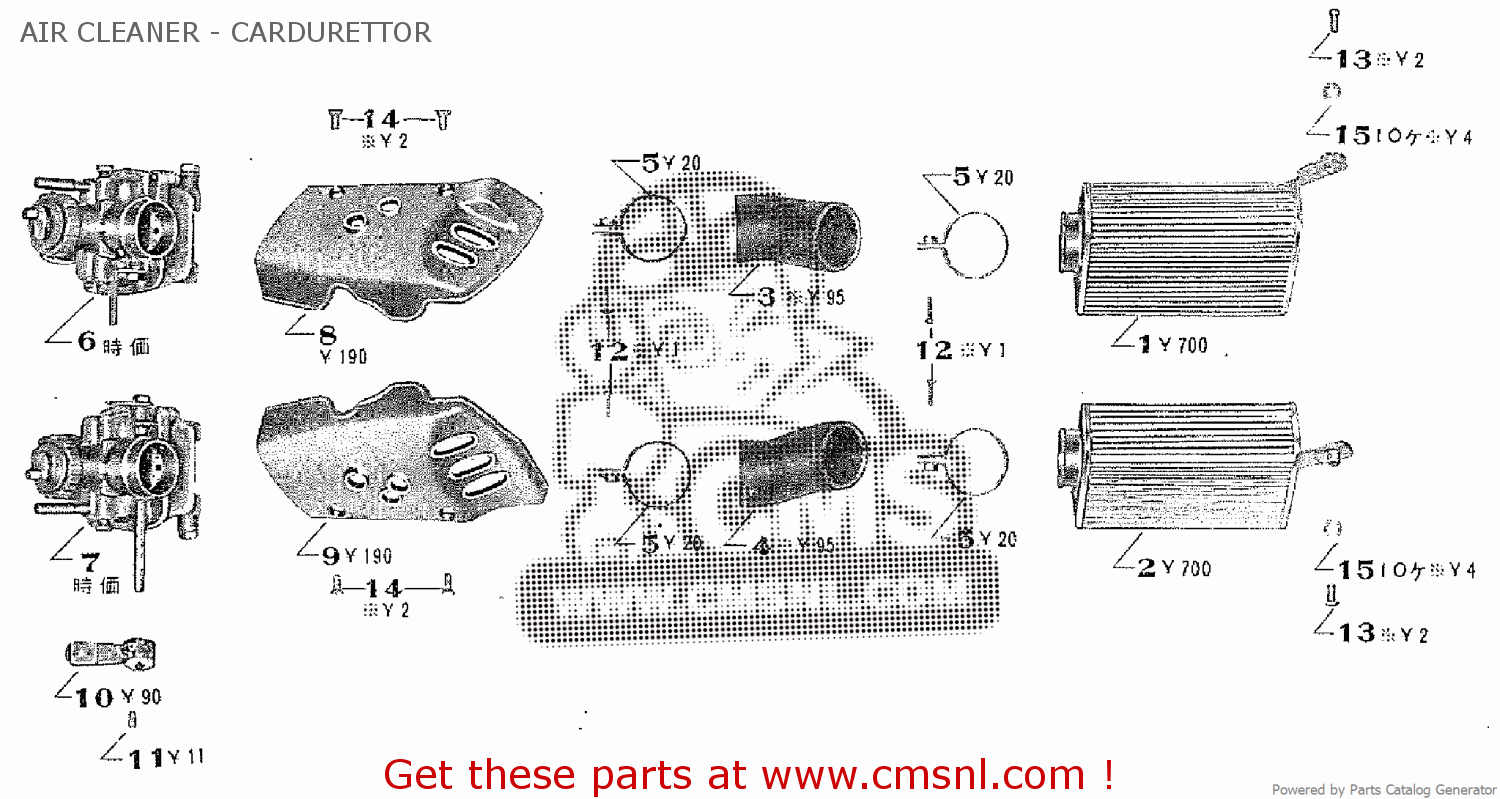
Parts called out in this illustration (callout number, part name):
1	RIGHT AIR CLEANER COMP.
2	LEFT AIR CLEANER COMP.
3	RIGHT SUCTION PIPE
4	LEFT SUCTION PIPE
5	SUCTION PIPE SET BAND
6	RIGHT CARBURETTOR ASSY.
7	LEFT CARBURETTOR ASSY.
8	RIGHT CARBURETTOR COVER
9	LEFT CARBURETTOR COVER
10	CHOKE LEVER
11	CHOKE LEVER SET SCREW
12	4X16 CROSS SCREW
13	6X12 CROSS SCREW
14	6X12 CROSS SCREW
15	6MM SPRING WASHER
